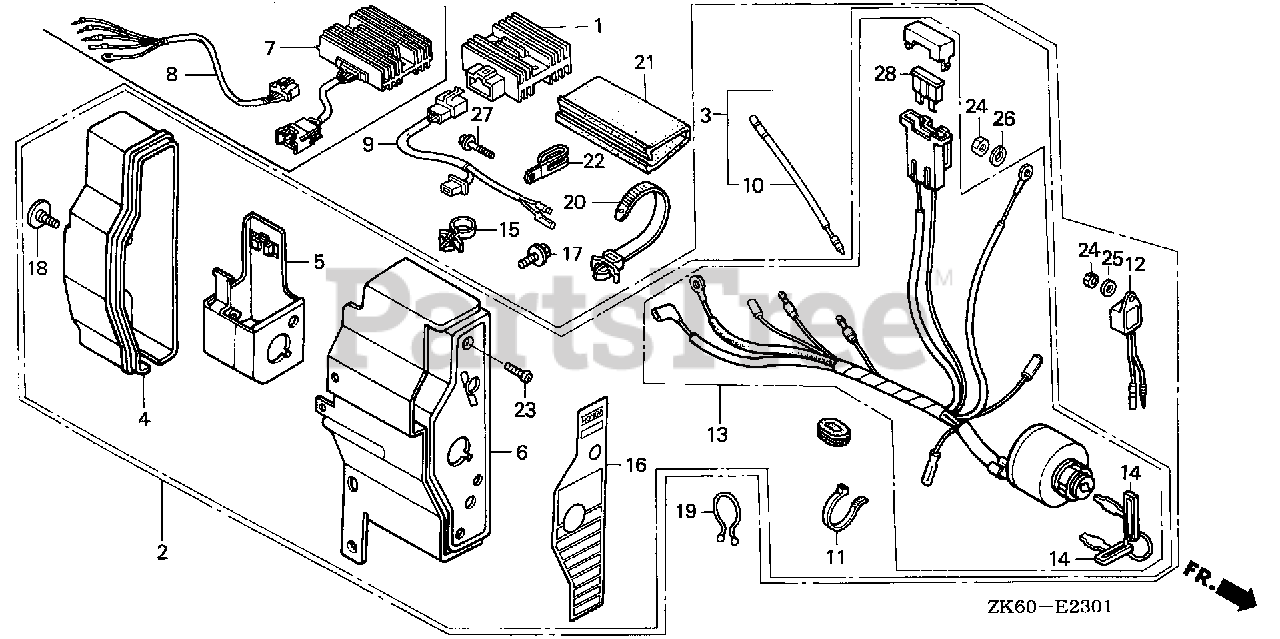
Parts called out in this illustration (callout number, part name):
2	BOX ASSY., CONTROL (18A) *NH1* (EXP-ALERT) (BLACK)
2	BOX ASSY., CONTROL (18A) *R280* (EXP-ALERT) (POWER RED)
4	CASE, CONTROL
5	BRACKET, CASE MOUNTING
6	PANEL, CONTROL *NH1* (BLACK)
6	PANEL, CONTROL *R280* (POWER RED)
7	RECTIFIER ASSY., REGULATOR (20A)
8	SUB-WIRE HARNESS ASSY.
10	SUB-WIRE HARNESS
12	ALERT UNIT, OIL
13	SWITCH ASSY., COMBINATION (18A-CHARGE)
14	KEY (HONDALOCK)
15	HOLDER, STOP SWITCH WIRE
16	MARK, CONTROL BOX (EXTERNAL-REGULATOR)
17	BOLT, FLANGE (6X12) (CT200)
18	SCREW, SPECIAL (6X12)
19	CLIP, PURSE LOCK
20	STRAP, CABLE (118MM) (BLACK)
21	TUBE, FASTENER (30MM)
23	SCREW, PAN (4X12)
24	NUT, HEX. (4MM) (SOURCE: VINTAGE PARTS INC.)
25	WASHER, PLAIN (4MM)
26	WASHER, SPRING (4MM)
28	FUSE, BLADE (25A)
